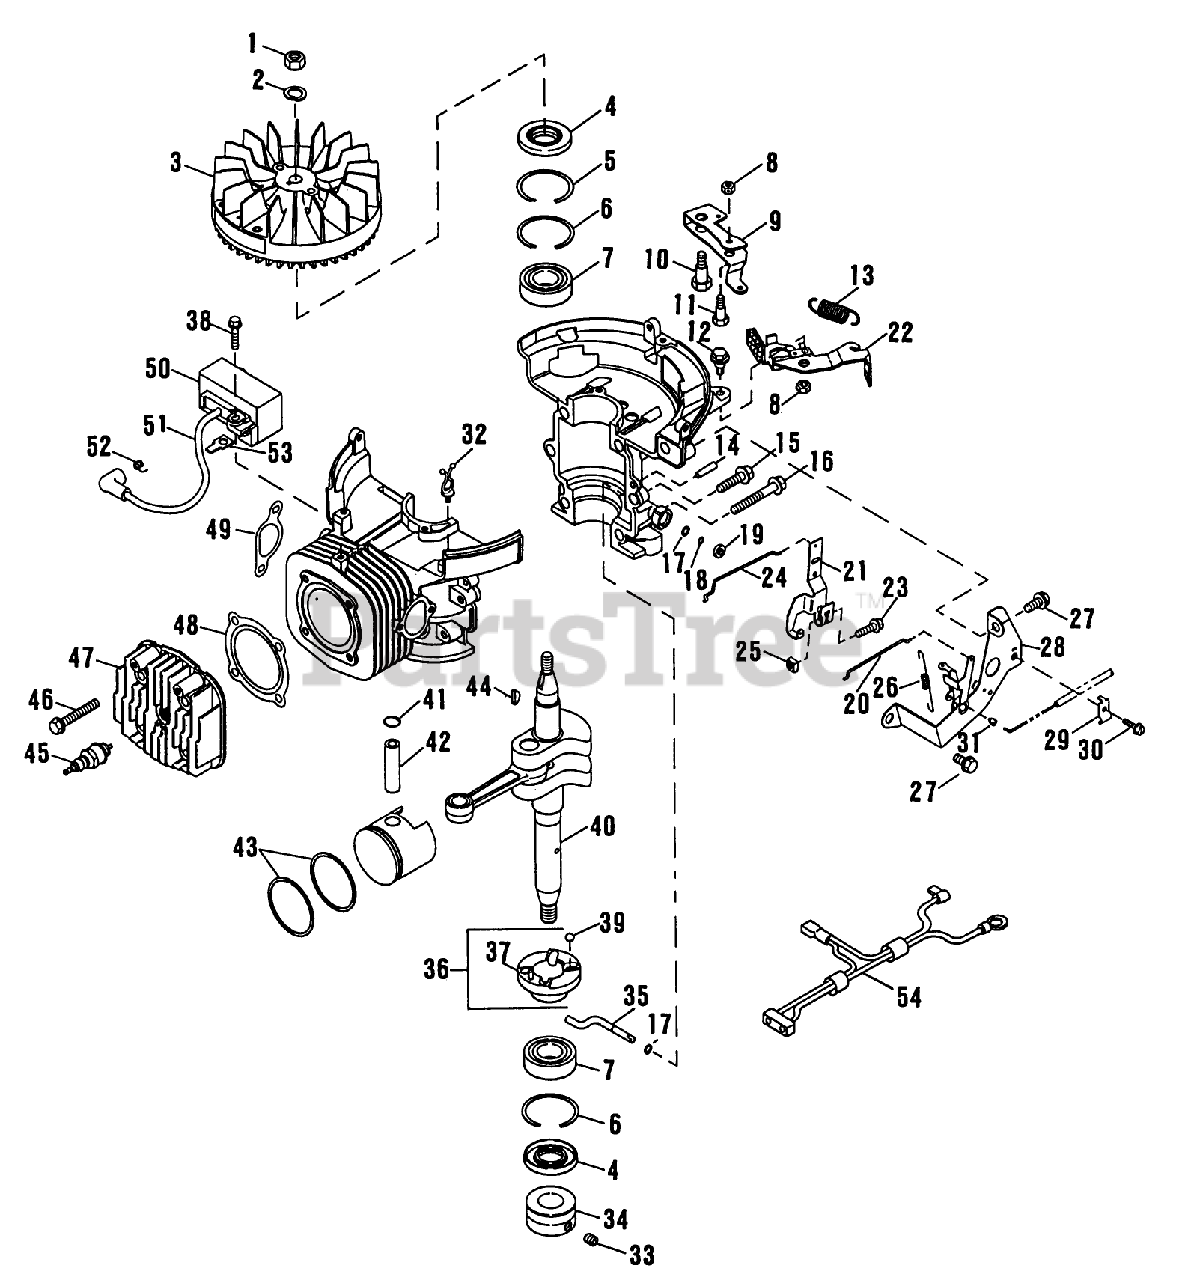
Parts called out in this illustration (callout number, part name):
1	NUT
4	SEAL - OIL SM
5	RING-RETAINER SM
7	BEARING-BALL SM
8	LOCKNUT E
9	ACT.BRAKE LVR. SM
10	SCREW-SHOULDER
13	SPRING-BRAKE
15	SCREW-H.W.HD. F
16	SCREW-HEX W.H. SM
18	RING-RETAINING
19	SEAL - OIL SM
24	ROD-THROTTLE SM
28	GOVNR BRKT SM
32	WIRE TIE SM
34	PULLEY-ENGINE
38	SCREW
43	RING SET S
44	KEY
46	SCREW
47	CYLINDER HEAD SM
49	GASKET - EXH SM
51	HI-TENS.LEAD
